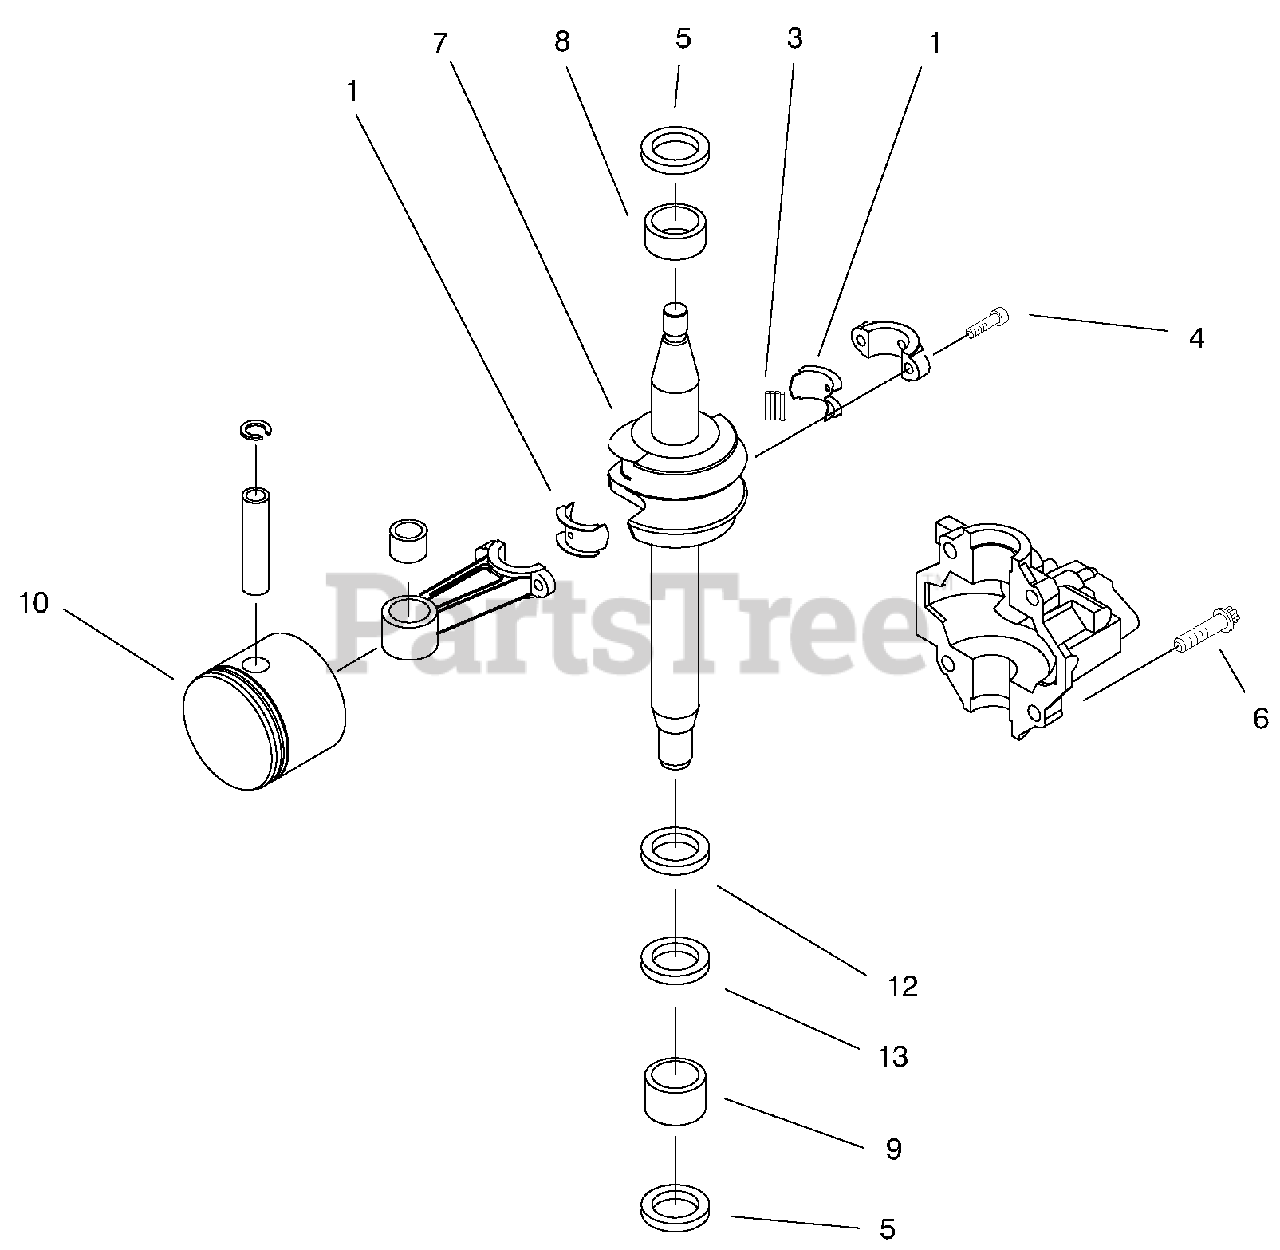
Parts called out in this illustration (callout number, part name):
1	Split Liner
3	Roller Strip
5	Oil Seal
6	Screw-HWH
7	Crankshaft
8	Bearing (Upper)
9	Bearing
10	ASM-Piston & Conn Rod
12	Bearing-Thrust
13	Washer-Thrust
